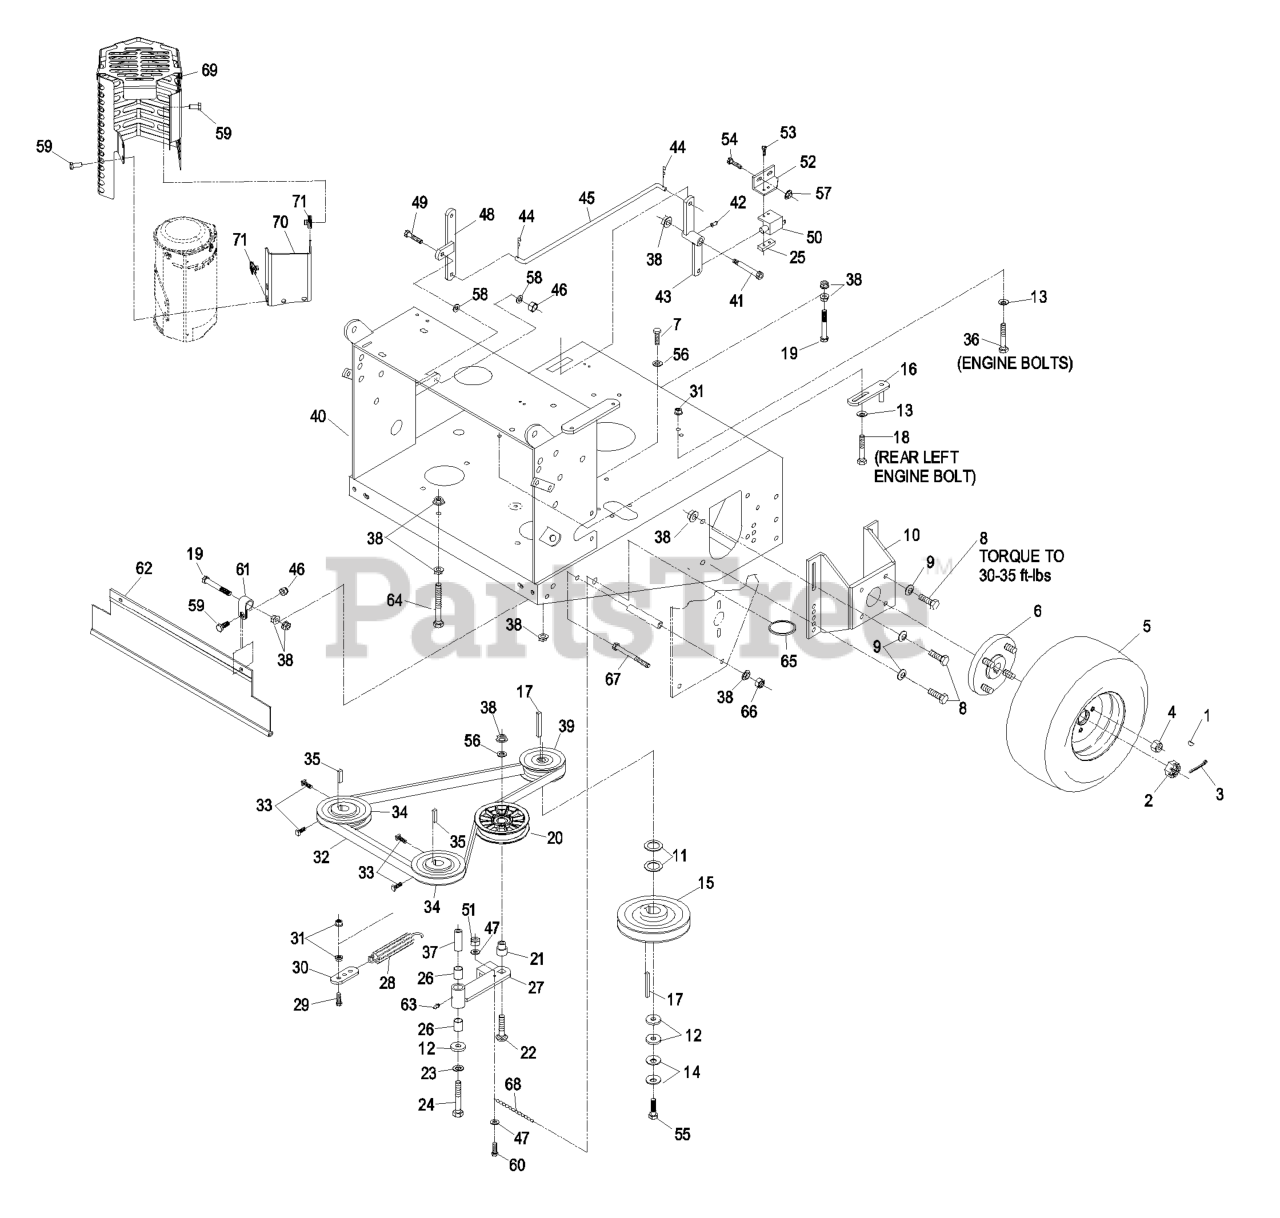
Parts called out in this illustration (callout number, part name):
1	KEY-WOODRUFF
2	NUT-HEX, SLOTTED
3	PIN-COTTER
4	NUT-LUG
5	WHEEL AND TIRE ASM
7	SCREW-HH
8	SCREW-HH
9	WASHER-BELLEVILLE
10	MOUNT-MOTOR
11	WASHER-SPACER
13	WASHER-SPRING
14	WASHER-SPRING
16	GUIDE-BELT
18	SCREW-HH
19	SCREW-HH
20	PULLEY-IDLER, FLAT
21	BUSHING-IDLER
22	SCREW-CARR
23	WASHER-LOCK
24	BOLT-CARR
25	PLATE-TAPPED
26	SLEEVE-BEARING
27	IDLER ARM ASM
28	SPRING-EXTENSION
29	SCREW-HH
30	ANCHOR-SPRING
32	BELT-COG
33	SCREW-SET
34	SHEAVE ASM
36	SCREW-HH
37	BUSHING
38	NUT-HHF, WHIZ
39	PULLEY
40	DECK,ENGINE W/DECALS
42	FITTING-GREASE, 90 DEG
43	BELLCRANK ASM
44	PIN-COTTER
45	LINKAGE-ENGAGE, BLADE
46	NUT-LOCK, NI
47	WASHER-FLAT
49	SCREW-HH
50	SWITCH-OPEN, NORMALLY
51	NUT-LOCK, NI
52	BRACKET-SWITCH, BLADE
53	SCREW-PPH
54	SCREW-HH
55	SCREW-HH
56	WASHER-FLAT
58	WASHER-PLAIN
59	SCREW-HH
60	SCREW-HSH
61	CLIP-LOOM
62	SHIELD-DRAG
63	FITTING-GREASE
64	SCREW-HH
65	RING-SPLIT
66	NUT-LOCK, NI
67	SCREW-HH
68	CHAIN-LINK, TWIST
69	MUFFLER SHIELD ASM
70	BRACKET-MUFFLER
